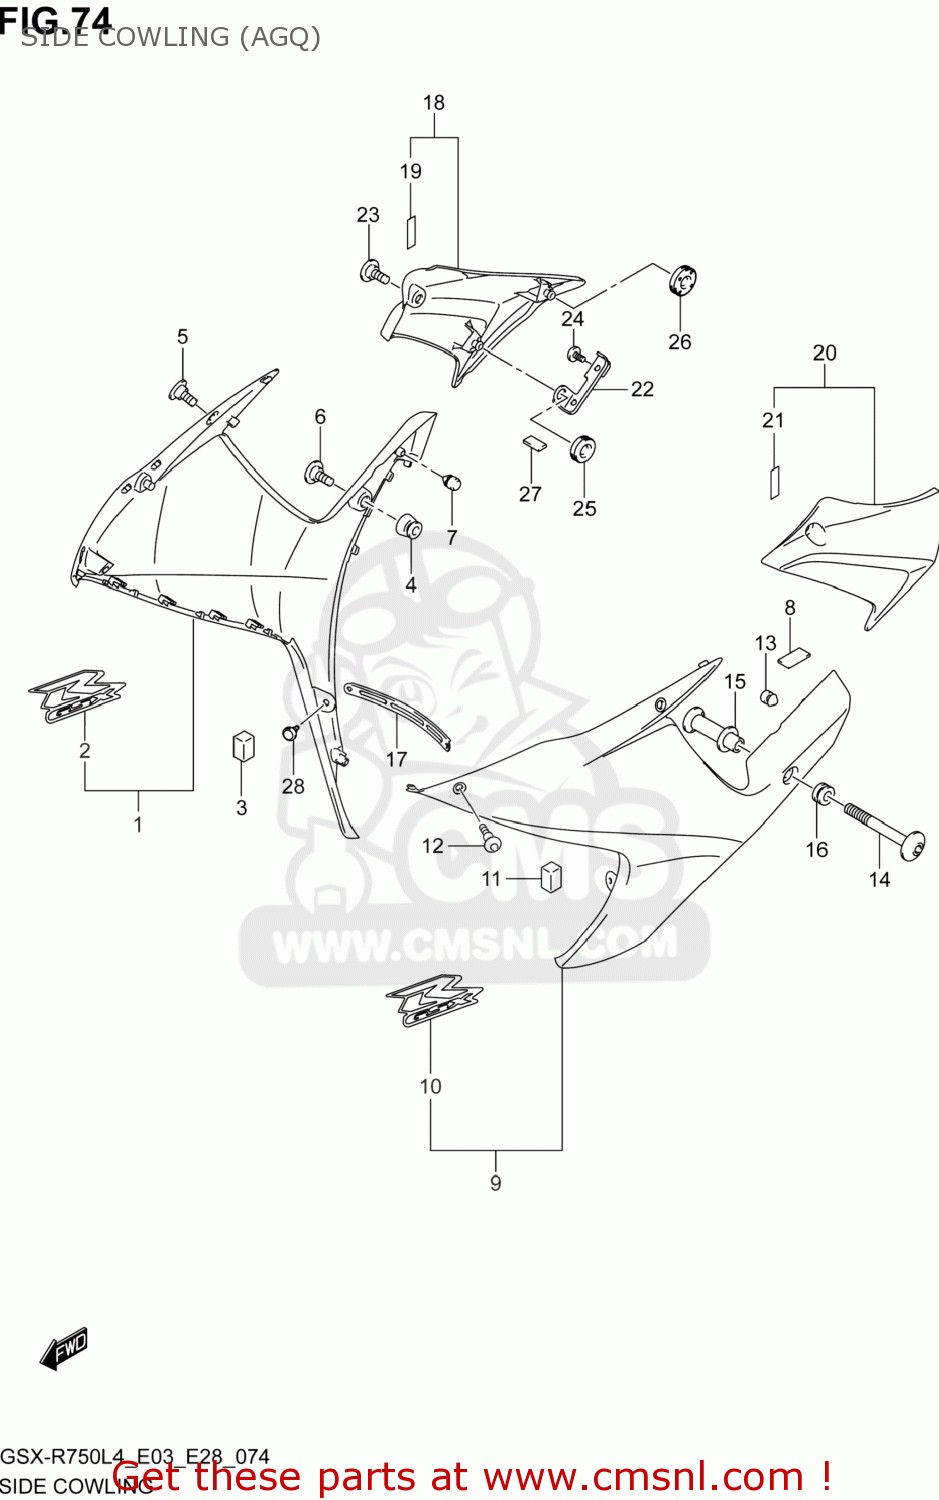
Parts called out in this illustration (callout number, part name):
1	COWLING,SIDE,R(BLUE)
2	EMBLEM,GSXR,R
3	CUSHION,SIDE COWL FR
4	CUSHION,UNDER COWLING,L
5	SCREW(5X13)
6	BOLT(6X20)
7	CUSHION
8	CUSHION,FUEL TANK NO.2
9	COWLING,SIDE,L(BLUE)
10	EMBLEM,GSXR,L
11	CUSHION,SIDE COWL FR
12	SCREW(5X13)
13	CUSHION
14	SCREW,SIDE COWL,L
15	SPACER,SIDE COWL,L
16	CUSHION
17	PLATE,UNDER COWL CTR
18	COVER,SIDE COWLING,R
19	TAPE(6X25X0.13)
20	COVER,SIDE COWLING,L
21	TAPE(6X25X0.13)
22	BRACKET,COVER SIDE,R
23	SCREW(5X13)
24	SCREW(6X12)
25	CUSHION
26	CUSHION
27	CUSHION
28	CLIP
